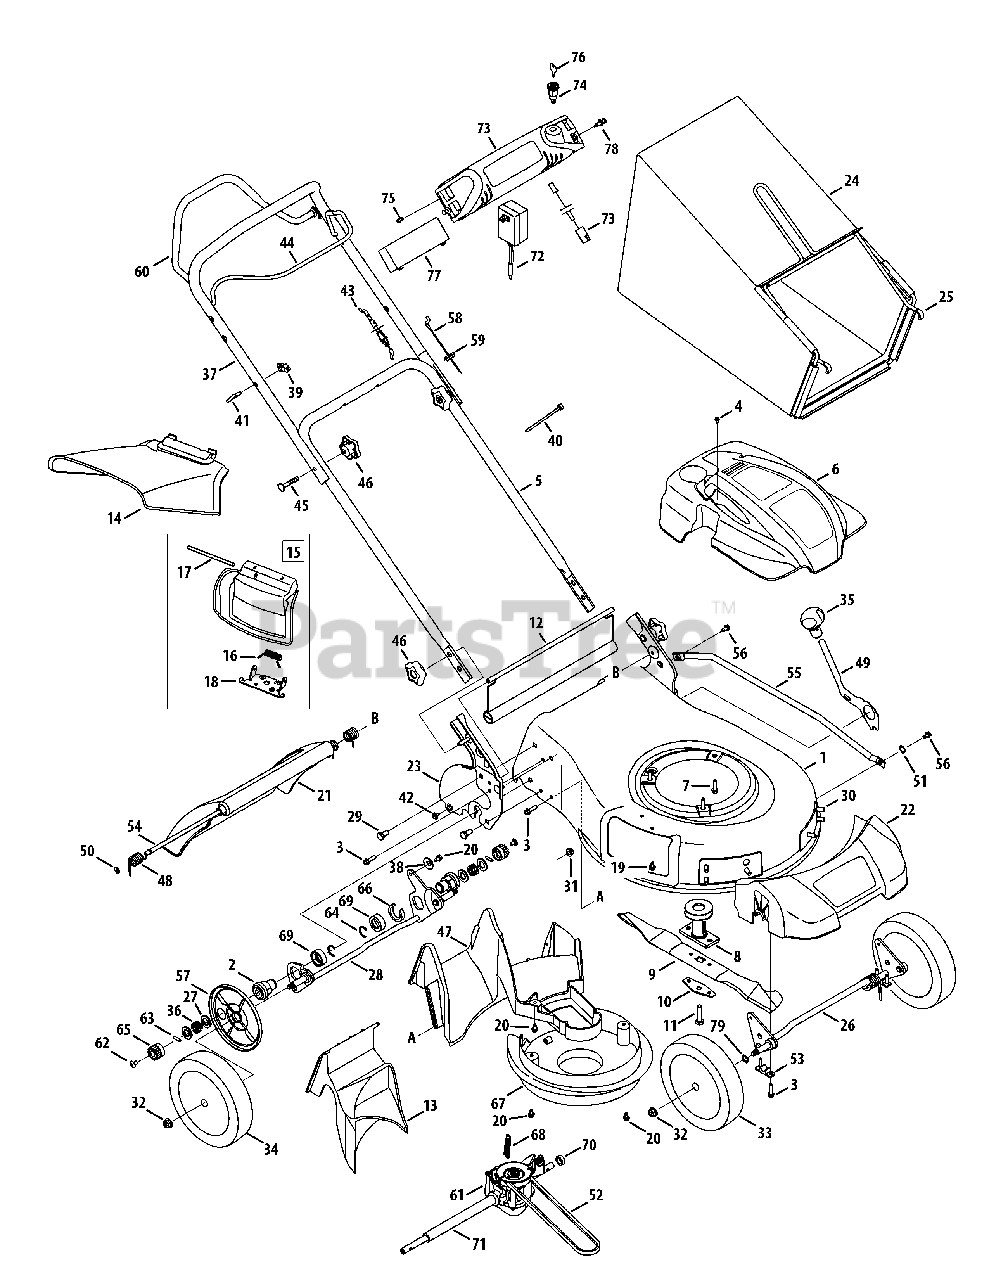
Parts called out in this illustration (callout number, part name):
2	Transmission Support Bearing
3	Screw, 1/4-15 x 1.000
4	Screw, HL, #12-16 x 1.00
5	Lower Handle
6	Engine Shroud
7	Screw, 3/8-16 x 1.00
8	Blade Adapter
9	Mulching Blade
10	Blade Bell Support
11	Screw, 3/8-24 x 1.50
12	Trailing Shield
13	Rear Mulch Plug
14	Side Discharge Chute
15	Mulch Plug (Incl. 16-18)
16	Torsion Spring
18	Chute Deflector Adapter
22	Front Cover
23	Handle Bracket - RH
23	Handle Bracket - LH
25	Grass Bag Frame
26	Front Bracket Assembly
27	Washer, Flat, .508 x 1.00 x .020
28	Self Propelled Bracket Ass’y
29	Hhcs, 5/16-18 x .625
30	Screw, 5/16-14 x .750
31	Nut, Flange Lock, 5/16-18
32	Nut, Flange Lock, 3/8-16
33	Front Wheel
34	Rear Wheel
36	Wave Spring
37	Upper Handle
38	Washer, Bell, .340 x .872 x .060
40	Cable Tie
41	Rope Guide
42	Screw, #10-16 x .500
43	Control Cable
44	Blade Control
45	Bolt Carriage, 5/16-18 x 2.0
47	Rear Baffle
48	Door Torsion Spring - RH
48	Door Torsion Spring - LH
49	Spring Lever
51	Wshr, Wave, .385 ID x .598 OD
53	Bushing, Lock, .505 Dia. X .62
54	Rear Door Pivot Rod
55	Cross Bracket
56	Scr., Shldr., 1/4-20 x .50
57	Wheel Dust Cover
58	Drive Cable
60	Drive Control
61	Transmission
62	Screw, 1/4-20 x .390
63	Dowel Pin
64	Retainer Ring
65	Spur Gear - RH
65	Spur Gear - LH
66	Spacer, Clip
67	Engine Baffle
68	Exten. Spring, .429OD x 2.515
69	Bearing Support Spacer
70	Sleeve Spacer, .550ID x .340 Lg.
71	Sleeve Spacer, .550ID x 7.97 Lg.
72	Battery Charger
73	Electric Start Harness Assembly
74	Key Switch
75	Screw, #10-16 x .750
77	Battery
79	Washer, Wave, .510 x .750 x .017
